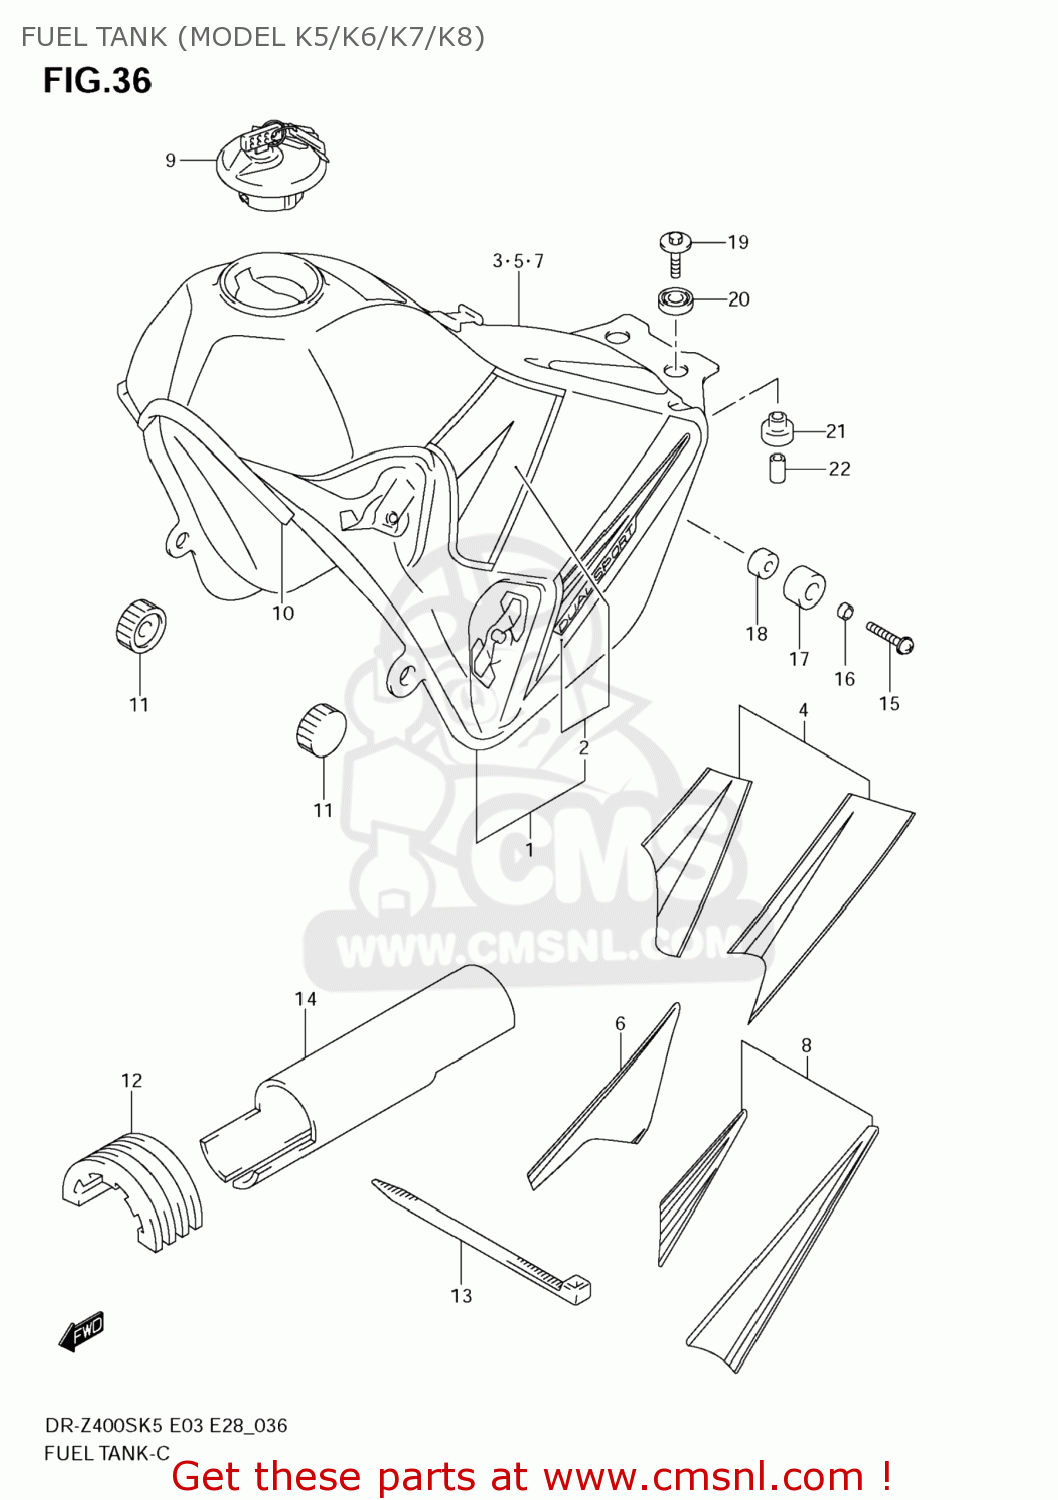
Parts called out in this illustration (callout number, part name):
1	TANK ASSY,FUEL(BLUE)
2	TAPE SET,FUEL TANK
3	TANK ASSY,FUEL(BLUE)
4	TAPE SET,FUEL TANK
5	TANK ASSY,FUEL(BLUE)
6	TAPE SET,FUEL TANK
7	TANK ASSY,FUEL(BLUE)
8	TAPE SET,FUEL TANK
9	CAP SET,FUEL TANK
10	MOLDING
11	CUSHION
12	CUSHION,FUEL TANK
13	CLAMP(L:300)
14	SHIELD,FUEL TANK
15	SCREW
16	SPACER(6.5X20X9)
17	CUSHION
18	SPACER(6.5X9X5)
19	BOLT(6X30)
20	CUSHION
21	CUSHION
22	SPACER(6.5X9X18)
